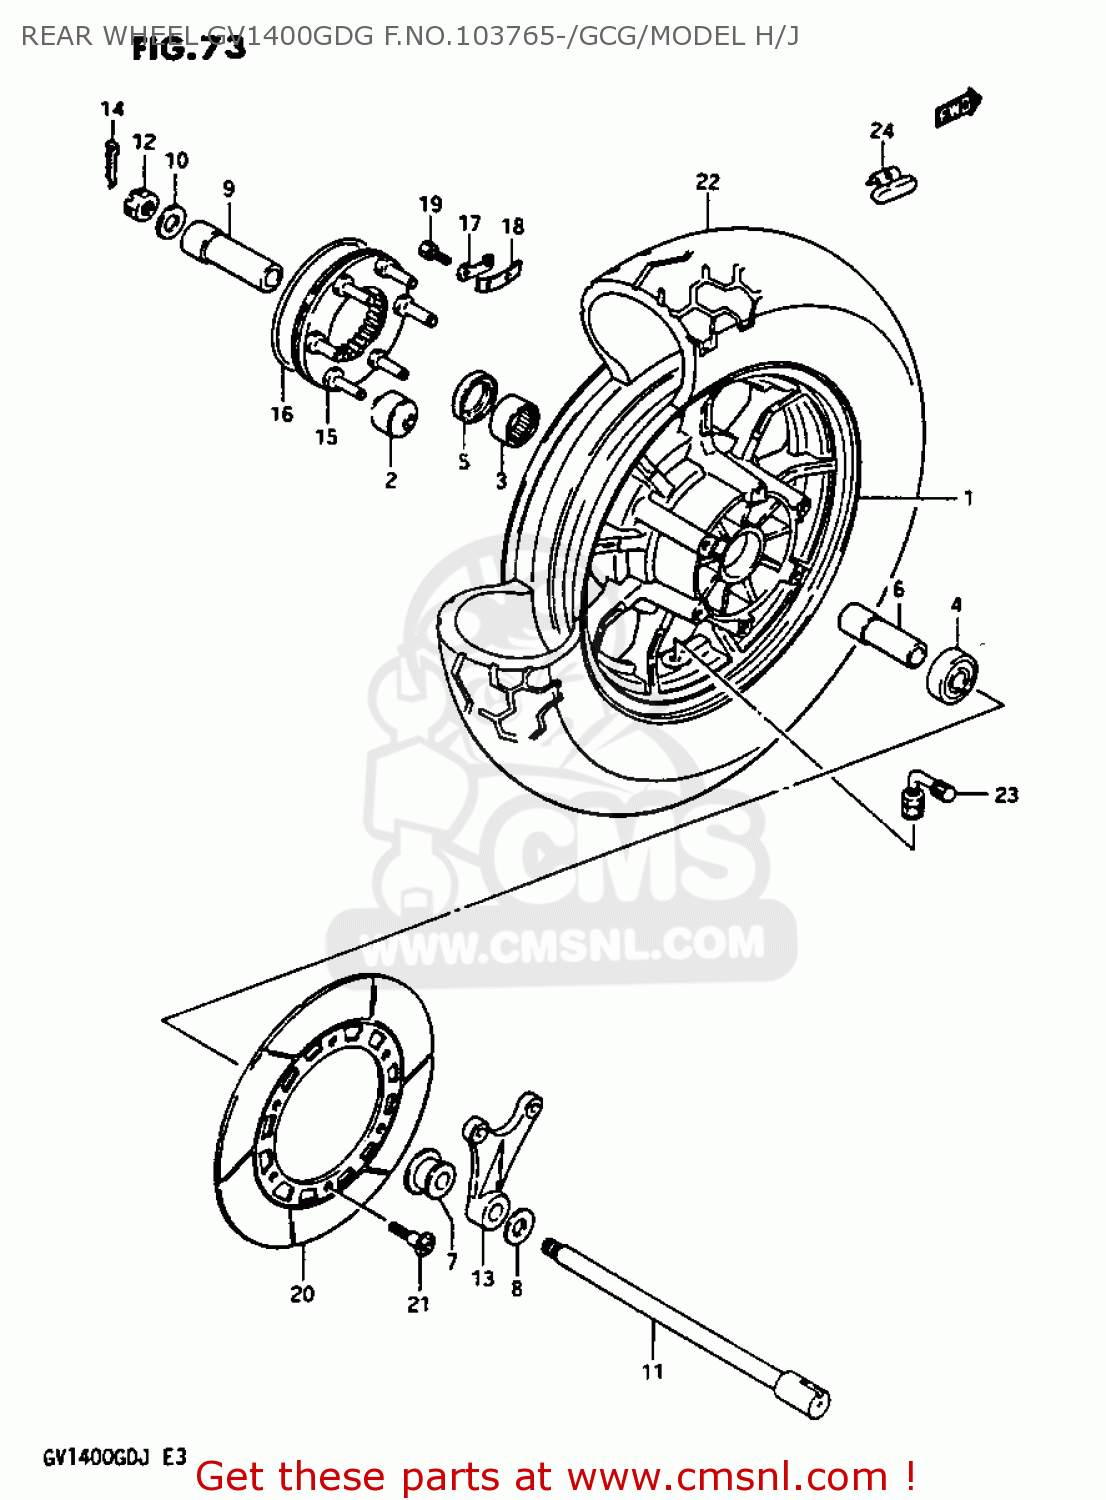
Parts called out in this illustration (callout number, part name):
1	WHEEL SET,REAR
2	BUSH
3	ROLLER BEARING (30X37X2
4	BEARING
5	SEAL,OIL(30X44X7)
6	SPACER,REAR HUB BEARING
7	SPACER COMP,REAR AXLE
8	WASHER,REAR AXLE,RIGHT
9	SPACER,REAR AXLE,LEFT
10	WASHER,HUB
11	AXLE,REAR
12	NUT 18MM
13	BRACKET,REAR CALIPER
14	PIN,COTTER
15	JOINT ASSY,RR HUB DRIVEN
16	O RING(D:2.1,ID:65)
17	WASHER
18	WASHER,THRUST(T:1.6)
19	BOLT(6X16)
20	DISC,REAR BRAKE
21	BOLT
22	TIRE 150/90-15 (T/L)
23	VALVE ASSY,WHEEL RIM(SA-1A)
24	BALANCER,WHEEL
